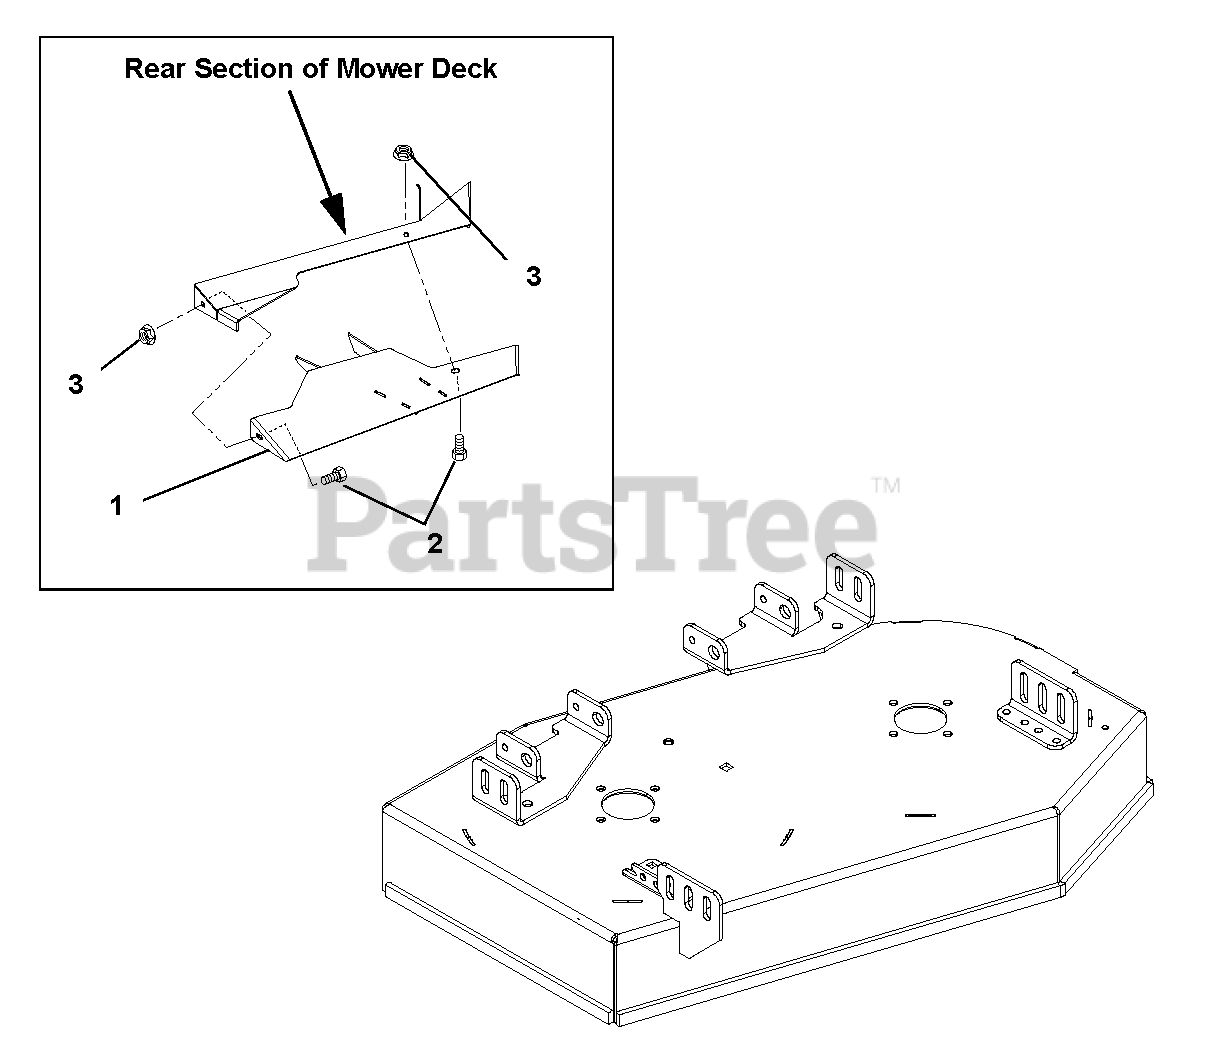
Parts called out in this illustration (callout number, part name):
1	34" Deflector Extension – Rear Discharge
2	Bolt, Hex .31-18 x .75 GR5 YZ
3	Nut, Locking Top Flange .31-18
